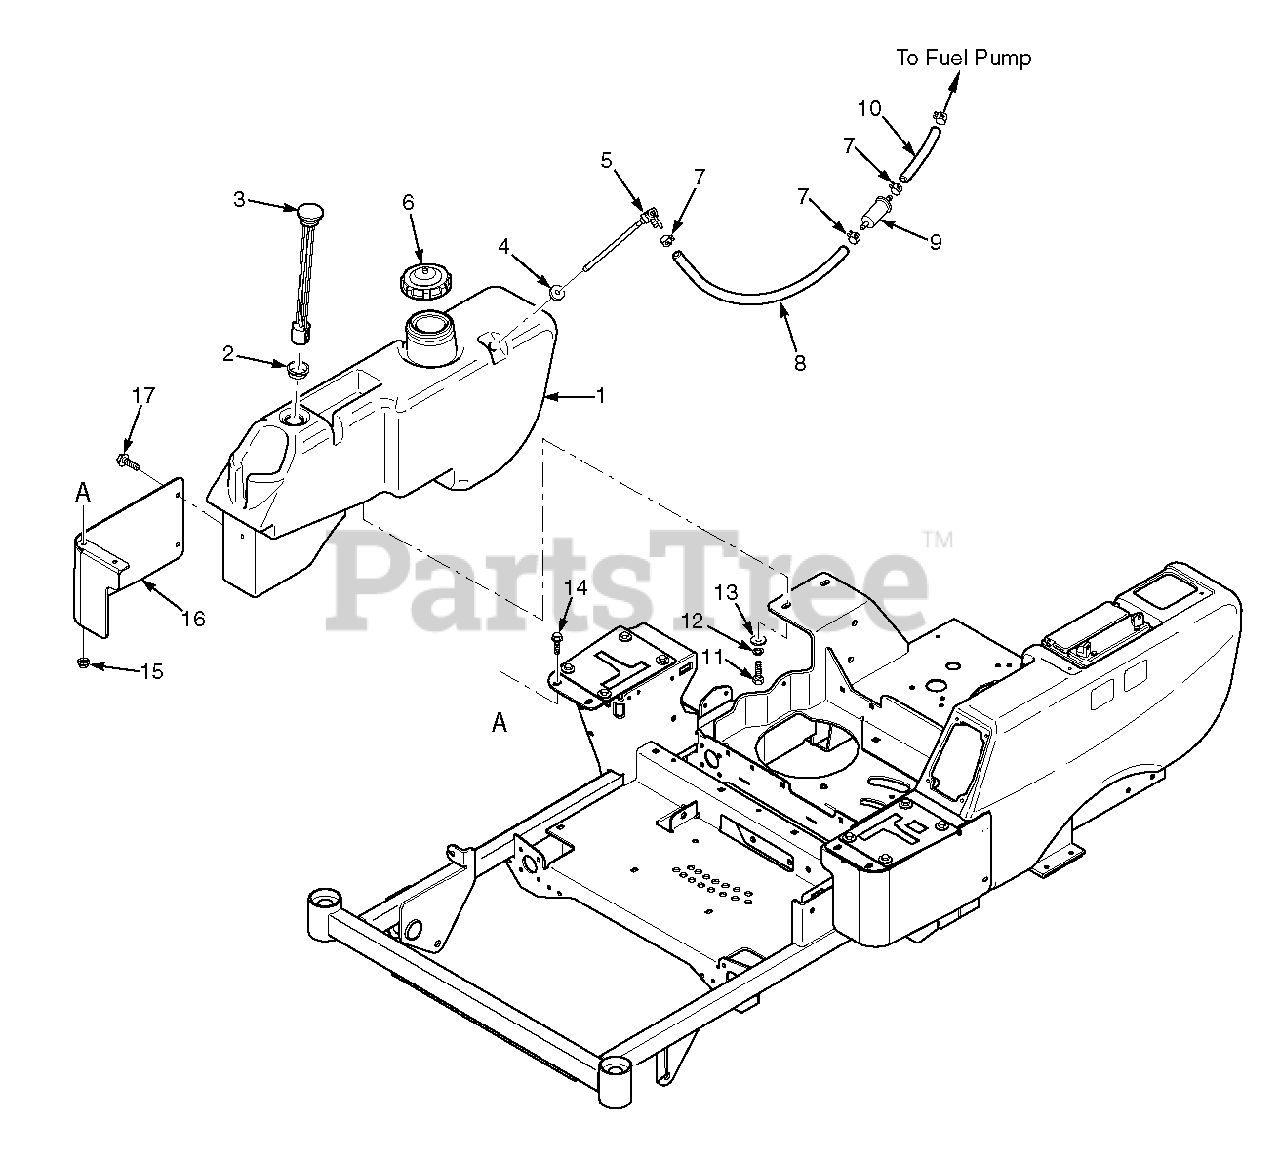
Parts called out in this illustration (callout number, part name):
1	Fuel Tanks Assembly
2	Grommet
3	Fuel Gauge Assembly
4	Bushing, 0.56 Dia. Viton
5	Fuel Tube Assembly
6	Fuel Cap
7	Clamp, Fuel Hose 1/4" ID
8	Fuel Hose, 1/4" ID Non-Perm
9	Fuel Filter
10	Fuel Hose
11	Bolt, Hex Head 5/16-18 x 3/4"
12	Lockwasher, 5/16- Spring
13	Flatwasher, 5/16-.375 x .875 x .083
14	Bolt, Hex Head 1/4-20 x 3/4" Serrated Flange
15	Nut, Serrated Flange 1/4-20
16	Control Cover, RH
17	Bolt, Hex Head 1/4-20 x 1/2" Serrated Flange
